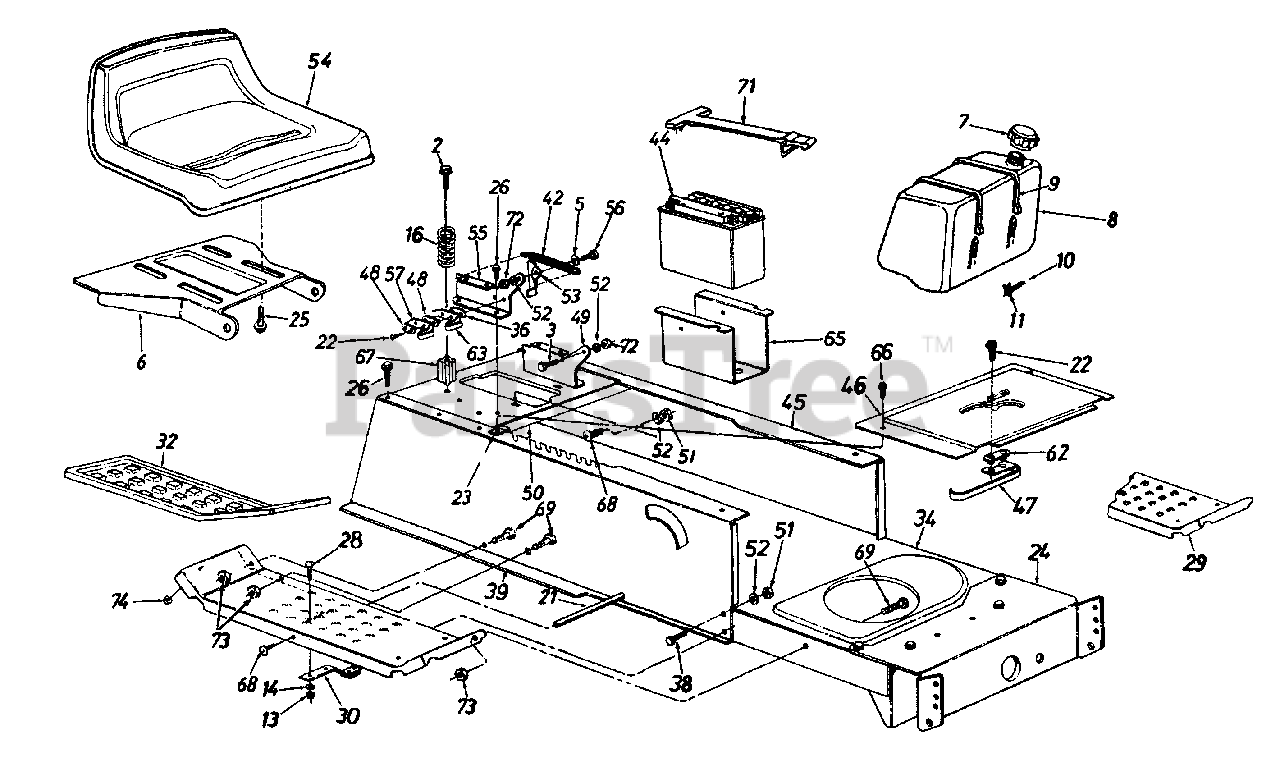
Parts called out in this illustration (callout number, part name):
2	Hex Tap Scr. 5/16-18 x 3.25"
3	Screw
5	Washer
7	Fuel Cap
8	Fuel Tank (12.5 H.P. & Smaller)
9	Tie Strap
10	Fuel Line
11	Hose Clamp
13	Hex Nut 1/4-20 Thd.
14	L-Wash. 1/4" I.D.
16	Compression Spring
21	Running Board Rod
22	Hex AB-Tap Scr. #8 x .50" Lg.
23	Speed Nut #10Z
25	Hex Tap Scr. 3/8-16 x .62" Lg.
26	Hex Wash. Hd. AB-Tap Scr. 5/16 x .75" Lg.
28	Carriage Bolt 1/4-20 x .62"
32	Rubber Foot Pad--L.H.
36	Insulator Boss Plate
38	Hex Bolt 5/16-18 x .75" Lg.
44	12-V Battery
47	Reverse Safety Switch
48	Insulator Plate
52	L-Wash. 5/16" I.D.
53	Seat Lift Brkt.
54	Seat 8-7/8" High
56	Shld. Bolt .437" Dia. x .268"
57	Spring Switch (Seat--Outer)
62	Insulator Nut Plate
63	Safety Switch (Seat--Inner)
66	Truss Mach. B-Tap Scr.#10 x .5" Lg.
67	Spring Spacer
68	Truss Mach. Scr. 5/16-18 x .75"
69	Hex Bolt 5/16-18 x .75" Lg.
71	Battery Retainer Strap
72	Hex Nut 5/16-18 Thd.
73	Hex Sems Nut 5/16-18 Thd.
74	Hex Sems Nut 1/4-20 Thd.
